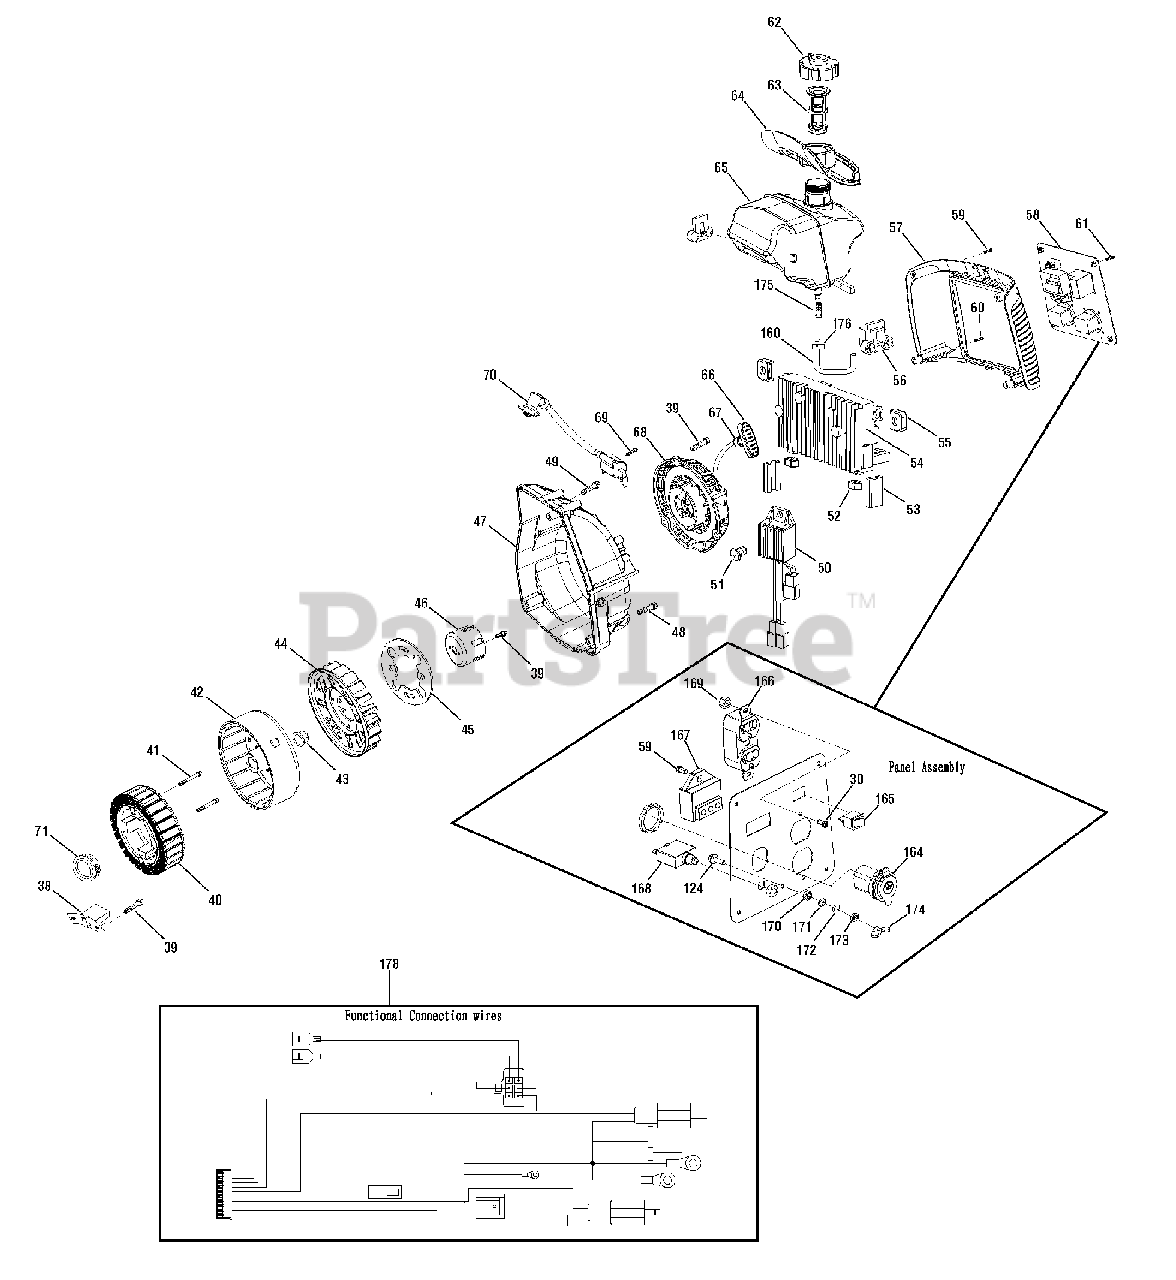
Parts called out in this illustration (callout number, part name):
30	BOLT
38	TRIGGER, Ingition
45	TERMINAL
47	COVER, Fan
48	BOLT
49	BOLT
50	REGULATOR, Voltage
51	BOLT
52	MOUNT, Vibration
53	MOUNT, Vibration
55	MOUNT, Vibration
56	MOUNT, Vibration
59	SCREW
60	SCREW
61	SCREW
63	FILTER, Filler Neck
64	PAD, Fuel Tank
67	GRIP
68	STARTER, Rewind
69	SCREW
71	SEAL, Oil
124	BOLT
166	OUTLET
167	LIGHT, Indicator
168	BREAKER, Circuit
169	*NUT
170	*NUT
171	WASHER
172	WASHER
173	WASHER
174	*NUT
175	FILTER, Fuel Tank
176	CLAMP
178	HARNESS, Wiring
